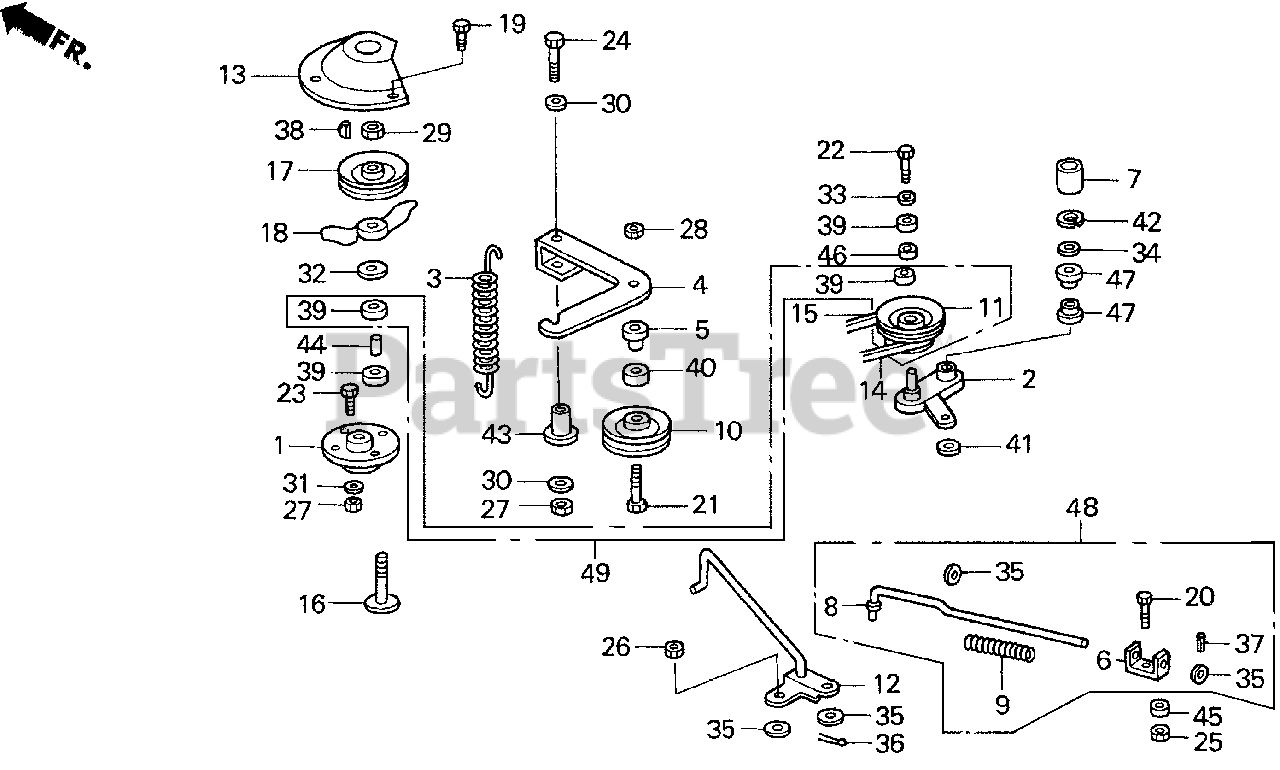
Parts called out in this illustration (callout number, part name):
1	HOUSING, BEARING
2	ARM, TENSION
3	SPRING, TENSIONER ARM
4	ARM, TENSION (DECK)
5	COLLAR, TENSION ROLLER
6	TENSIONER SET
7	CAP, PIVOT
8	ROD, TENSIONER (NOT AVAILABLE)
9	SPRING, TENSIONER
10	ROLLER, TENSIONER
11	PULLEY, DRIVEN
12	HANDLE, TENSION
13	COVER, L. BELT
14	V-BELT, BLADE
15	V-BELT, DECK
16	SHAFT, BLADE
17	PULLEY, BLADE
18	FAN, BLADE PULLEY
19	HEIGHT ADJUST SET
20	BOLT, CARRIAGE (8X25)
20	BOLT, HEX. (8X25)
21	BOLT, FLANGE (10X40)
22	BOLT, FLANGE (10X20)
23	BOLT, HEX. (8X30)
24	BOLT, HEX. (8X70)
25	NUT, FLANGE (8MM)
26	NUT A, LOCK (8MM)
27	NUT B, LOCK (8MM)
28	NUT, LOCK (10MM)
29	NUT, LOCK (3/4"-16)
30	WASHER, TENSIONER ARM
31	WASHER, HOUSING MOUNT (NOT AVAILABLE)
32	WASHER, SPINDLE
33	WASHER, FLAT (11X34X3)
34	WASHER, FLAT (1.25")
35	WASHER, FLAT (8.4X17X1.6)
36	PIN, DRAFT ARM COTTER
37	PIN, SPRING
38	KEY, WOODRUFF
39	BEARING A, CUTTER DECK
40	BEARING B, CUTTER DECK
41	RETAINER, FRAME
43	BUSHING, IDLER PIVOT
44	COLLAR, SPACER
45	BUSHING, PIVOT IDLER
46	COLLAR, DRIVEN PULLEY
47	BUSHING, DRIVE
48	TENSIONER SET
49	PULLEY SET
